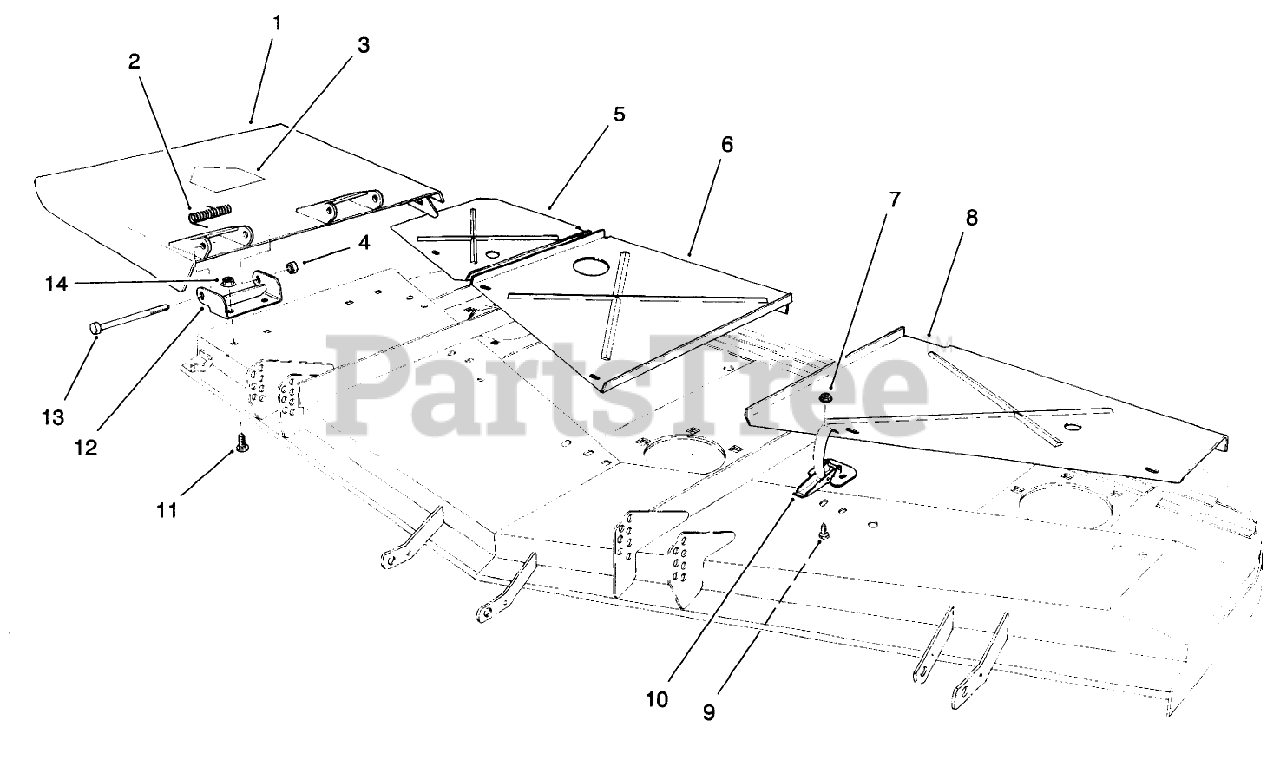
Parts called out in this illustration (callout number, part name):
1	Deflector (Incl. Ref. #3)
2	SPRING
3	DECAL-DANGER
4	NUT-HEX
5	Cover-Deck R.H.
6	Cover-Deck Center
7	NUT-LOCK, FLANGE
8	Cover-Deck L.H.
9	SCREW-HWH
10	CLAMP-SLOTTED
11	SCREW-CARR
12	Bracket-Hinge
13	SCREW-HH
14	NUT-HHF, WHIZ
